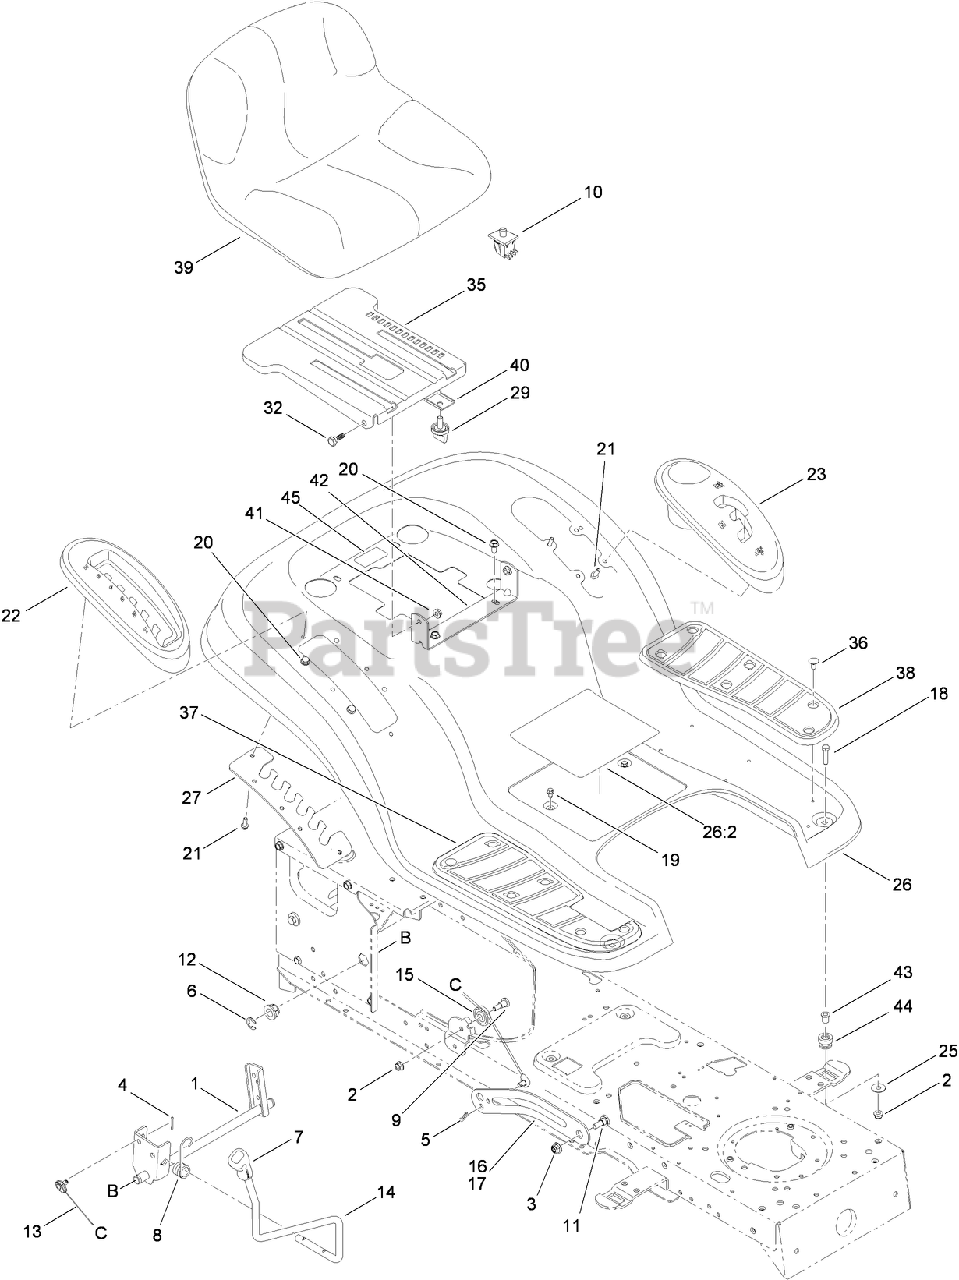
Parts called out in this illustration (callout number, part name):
1	LIFT SHAFT ASM
2	NUT-LOCK, FLANGE
3	NUT-LOCK, FLANGE
4	PIN-COTTER
5	PIN-COTTER
6	RING-E
7	GRIP-HANDLE
8	SPRING-TORSION
9	BOLT-SHOULDER
10	SWITCH-SEAT
11	BOLT-SHOULDER
12	BEARING-FLANGE
13	CABLE-LIFT
14	HANDLE-LIFT
15	PULLEY-ROLLER
18	SCREW-HH
19	SCREW-HWHTF
20	SCREW-TAP
21	SCREW-TAP
22	COVER-LIFT, LEVER
23	COVER-SHAFT (W/CUP HOLDER)
25	WASHER-FLAT
26	FENDER WITH DECAL
26:2	DECAL-SAFETY
27	BRACKET-ADJUSTING, LIFT
32	BOLT-SHOULDER
35	BRACKET-MOUNT, SEAT
36	CLIP-RATCHET, FASTENER
37	PAD-FOOT, RH
38	PAD-FOOT, LH
40	BRACKET-KNOB, ADJUSTMENT
41	NUT-LOCK, FLANGE
42	BRACKET-PIVOT, SEAT
43	SPACER
44	GROMMET
45	DECAL-TORO HOTLINE
